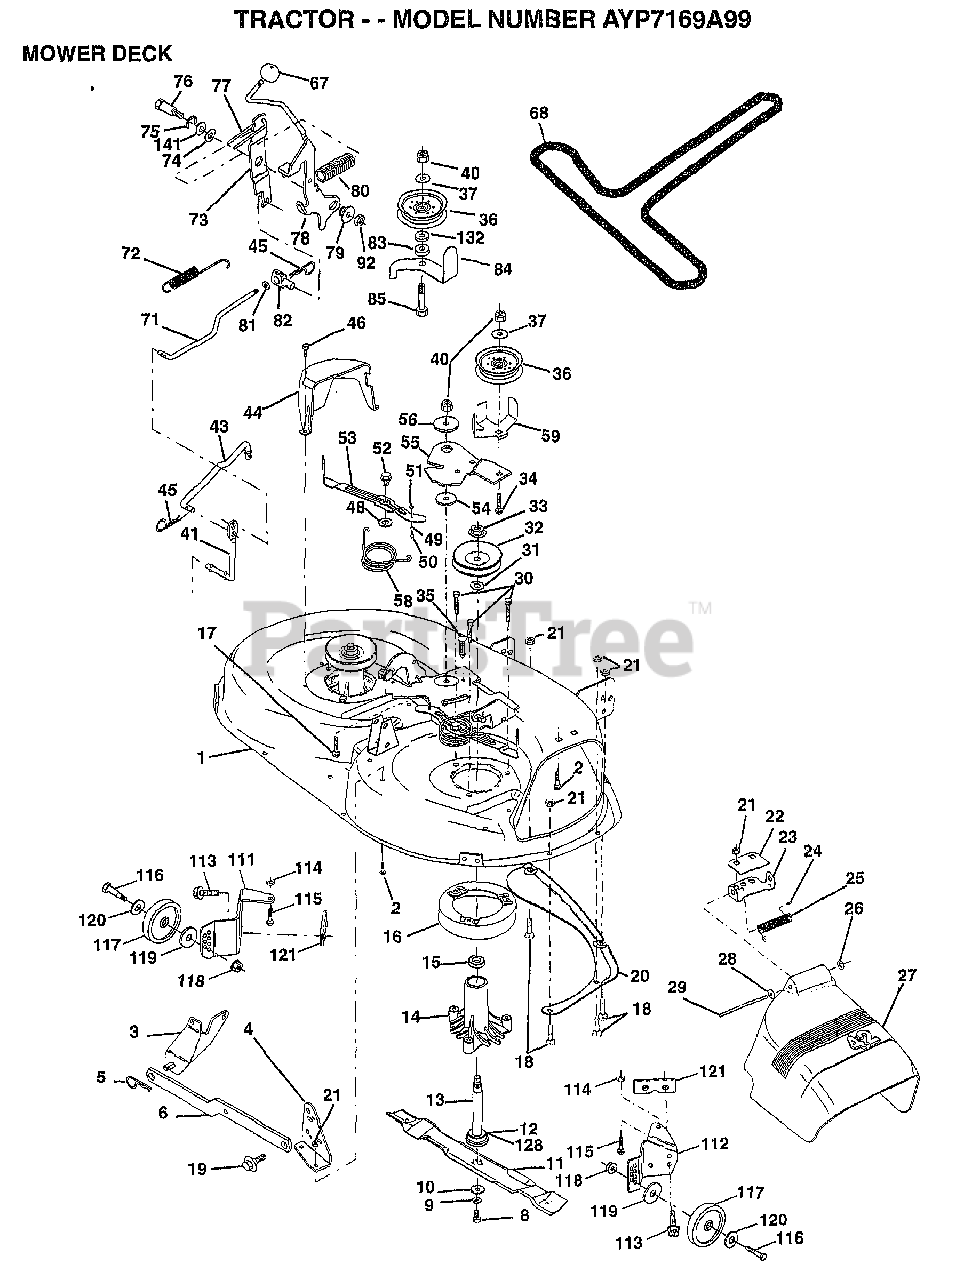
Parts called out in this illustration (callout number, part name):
1	"HOUSING ASSY.42"""
2	BOLT
3	BRKT ASM SWAY BAR
4	BRKT DECK SW BAR
8	BLADE BOLT
10	WASHER.HARD.BLADE
11	"BLADE.42"" MULCHER"
12	BEARING.BALL
14	HSG ASM MANDREL
15	BEARING
16	STRIPPER RND MWR
17	BOLT RDHD 3/8-16
18	BOLT
19	BOLT SHD 5/16-18
20	BAFFLE VORTEX 42
22	STIFFENER BRKT
23	DEFLECTOR BRKT
24	CAP-SLEEVE LT
25	SPRING TORSION
26	NUT PUSH M
27	DEFLECTOR.SHIELD
28	WASHER
29	HINGE ROD
30	"SCREW-THD ROLL,WA"
31	WASHER
32	PULLEY.MANDREL.42
34	BOLT
35	XMAS TREE FASTNER
36	FLAT IDLER PULLEY
37	WASHER
41	PIVOT ROD
43	ROD CLUTCH W/NIBS
44	GUARD MAND LH BLK
45	RETAINER M
46	SCREW.1/4-20X5/8
48	HARD SMALL WASHER
49	ROLLER ASM-CAM
50	SHOULDER BOLT
51	LOCKNUT
52	BOLT.SHLD.5/16-18
53	BRAKE PAD ARM ASM
54	HARDENED WASHER
55	ARM-IDLER
56	SPACER RETAINER
58	SPRING TORSN BRAK
59	GUARD IDLER TUV
67	KNOB.RD.7/16-14
68	BELT.V.T-PATH
71	ROD CLUTCH 38/42
72	RETURN SPRING
73	CLUTCH ARM SECOND
74	WASHER
75	RING
76	SHOULDER BOLT
77	SPRING KEEPER
78	LEVER.ASM.CLUTCH
79	BUSHING
80	SPRING.CLUTCH.MWR
81	NUT
82	TRUNION ADJ
83	WASHER
84	"KEEPER-BELT,FIXED"
85	BOLT
92	NUT
111	BRACKET.GWHL.LH.
112	BRACKET.GWHL.RH.
113	SCREW
116	BOLT M
117	WHEEL.GAGE.BLK.PL
118	LOCKNUT
119	WASHER
120	WASHER
121	BRACKET.EXTRD.GWL
128	WASHER.FELT.
132	WASHER GT
141	WASHER .T
